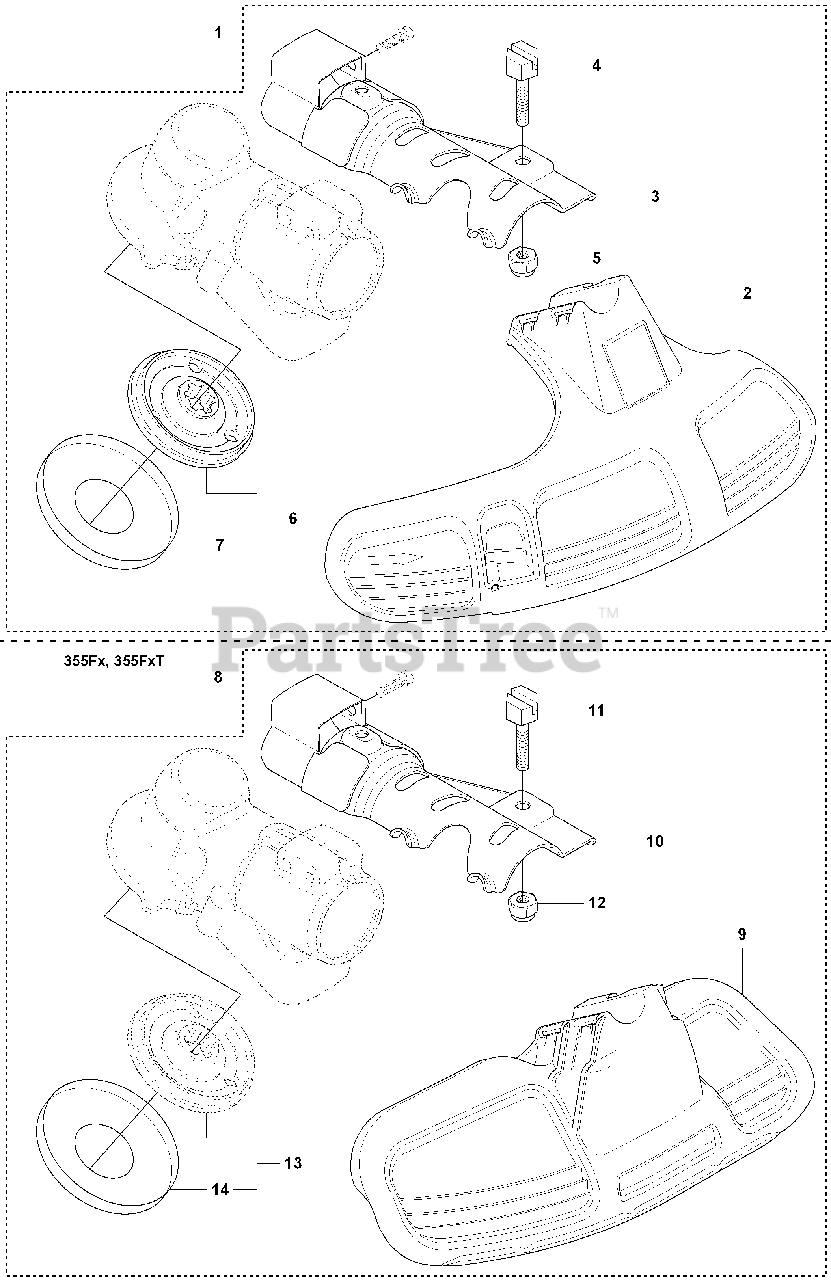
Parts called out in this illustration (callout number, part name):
2	PROTECTION
3	ATTACHMENT PLATE
5	LOCKNUT M6
7	GRASS SEALING
9	BLADE GUARD GRASS
10	ATTACHMENT PLATE
12	LOCKNUT M6
14	GRASS SEALING
